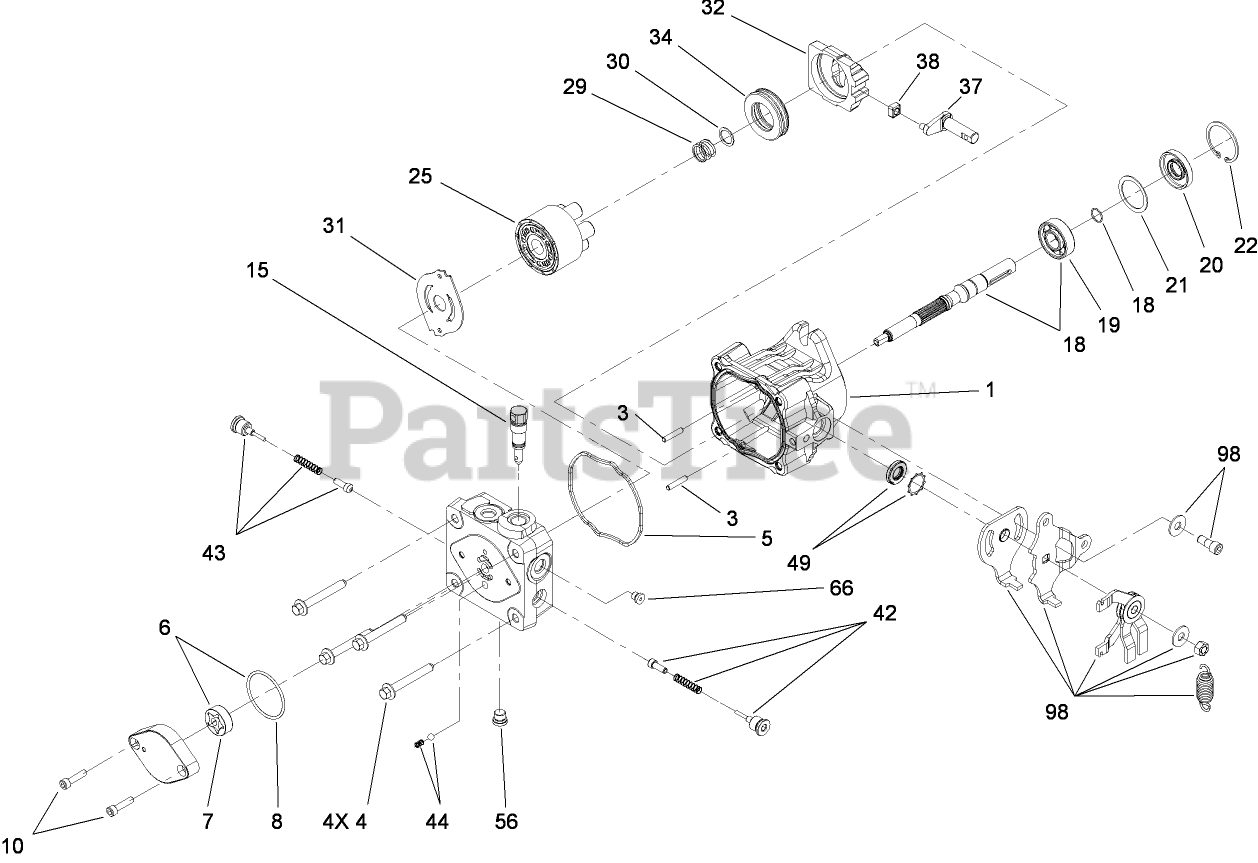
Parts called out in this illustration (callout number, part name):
1	HOUSING KIT
3	PIN-HEADLESS, STRAIGHT
4	BOLT-HF
5	O-RING
6	CHARGE PUMP KIT
7	GEROTOR ASM
8	O-RING
10	CAPSCREW
15	BYPASS VALVE KIT
18	INPUT SHAFT KIT
19	BEARING-BALL
20	SEAL-LIP
21	SPACER
22	RING-RETAINING
25	CYLINDER BLOCK KIT
29	SPRING-BLOCK
30	WASHER-THRUST
31	Plate-Valve
32	SWASHPLATE-VARIABLE
34	BEARING-THRUST
37	TRUNNION ASM
38	GUIDE-SLOT
42	VALVE-CHECK (W/POPPET)
43	VALVE-CHECK, W/POPPET
44	CHARGE RELIEF VALVE KIT
49	TRUNNION SEAL / RETAINER KIT
56	PLUG-HSH
66	PLUG-HSH
98	RETURN KIT
